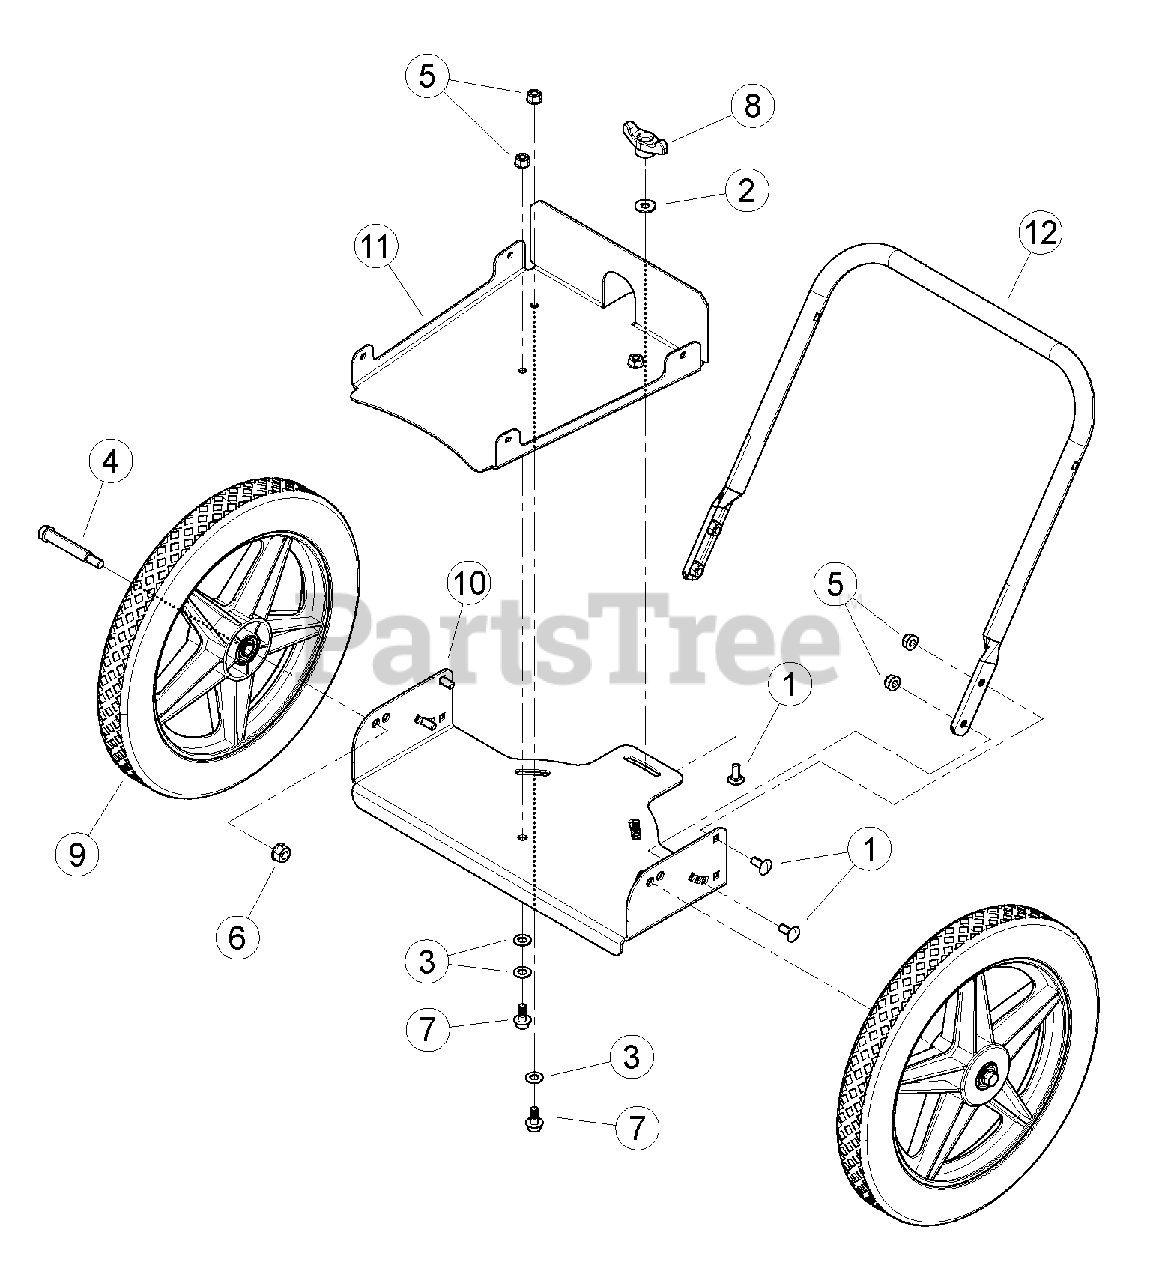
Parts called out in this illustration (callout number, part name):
1	BOLT, 5/16-18 X 3/4 SN GR5 CRG
2	WASHER, 5/16 FLAT
3	WASHER, NYLON .390 ID X .750 OD
4	BOLT, 3/8-16 X 3-1/4 FLANGED SHOULDER
5	NUT, 5/16-18 NYLOCK FLANGE
6	NUT, 3/8-16 NYLOCK FLANGE
7	BOLT, 5/16-18 X 3/4 ZP FLANGE SHOULDER
8	KNOB, 5/16-18 FEEM TEE
9	WHEEL, TRIMMER 15 X 1.75
10	PLATE, TRIMMER AXLE
11	PLATE, TRIMMER BASE PUSH
12	HANDLE BAR, LOWER TRIMMER PAINTED
